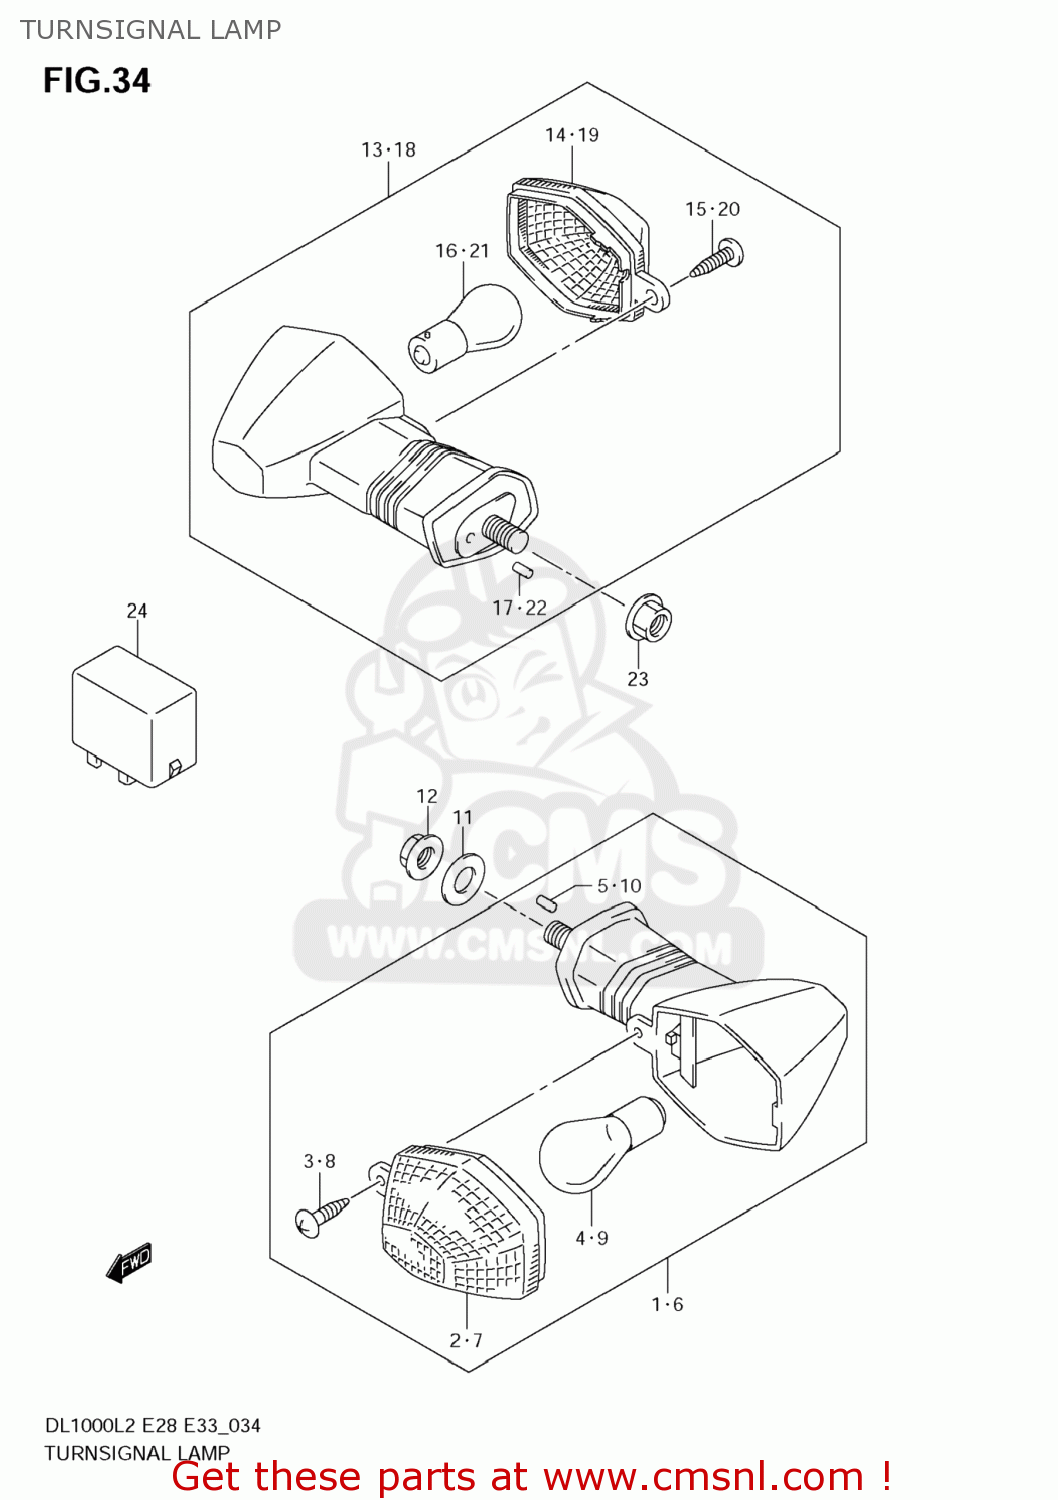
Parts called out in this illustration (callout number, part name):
1	LAMP ASSY,FR TURN SIGNAL,R
2	LENS
3	SCREW
4	BULB(12V21W,AMBER)
5	PIN(4.5X9.5)
6	LAMP ASSY,FR TURN SIGNAL,L
7	LENS
8	SCREW
9	BULB(12V21W,AMBER)
10	PIN(4.5X9.5)
11	WASHER(12.5X30X1.6)
12	NUT
13	LAMP ASSY,RR TURNSIGNAL,R
14	LENS
15	SCREW
16	BULB(12V21W,AMBER)
17	PIN(4.5X9.5)
18	LAMP ASSY,RR TURNSIGNAL,L
19	LENS
20	SCREW
21	BULB(12V21W,AMBER)
22	PIN(4.5X9.5)
23	NUT
24	RELAY ASSY,TURNSIGNAL LAMP
